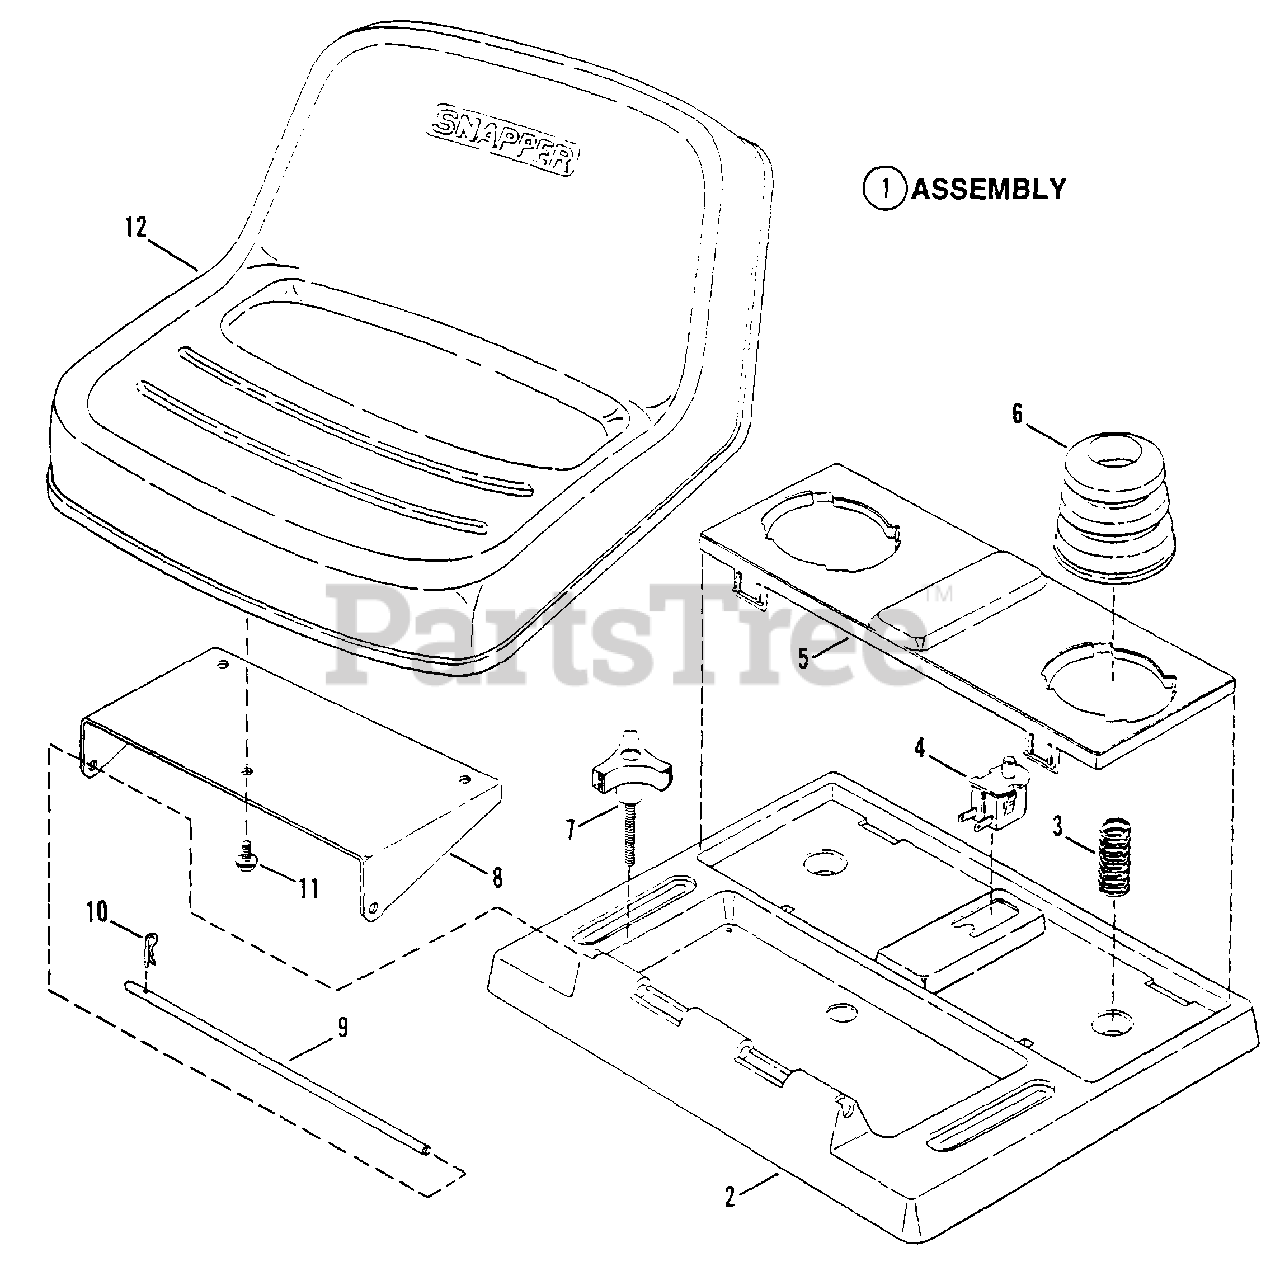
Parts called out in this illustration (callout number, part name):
1	ASSEMBLY, Seat Support
2	SUPPORT, Seat
3	SPRING
4	SWITCH, Seat
5	HOLDER, Cushion
6	CUSHION, Seat
7	KNOB, Seat Adjustment
8	BRACKET, Seat Support
9	ROD, Seat Hinge
10	PIN, Hair
11	BOLT, 5/16-18 x 1/2" Hex Flange Lock
12	SEAT, Operator's
